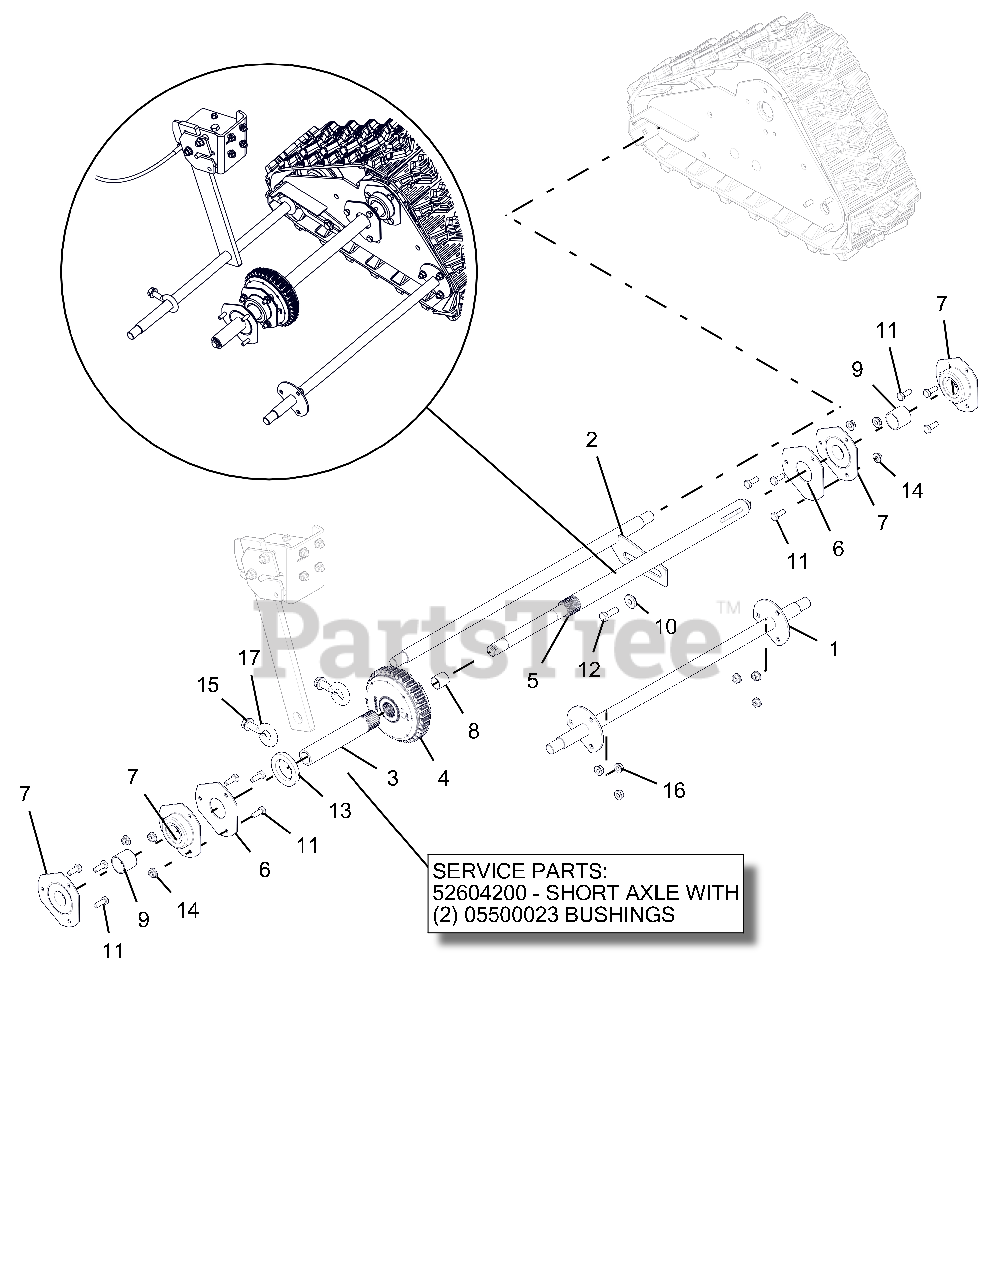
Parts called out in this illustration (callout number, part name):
1	AXLE, FRONT - PRO
2	AXLE, REAR - PRO TRACK
3	AXLE, SHORT-TRACK DIFFERENTIAL
3	AXLE, SHORT-TRACK W/BUSHINGS
3	BSHG-SLV .706X.764X.75 BRZ
4	DIFFERENTIAL, AUTOMATIC
5	AXLE, LONG-PRO AUTO DIFF
6	PLATE, BEARING SPACER
7	BRG-FLG 1.003/1.000 3 BOLT
8	BSHG-SLV .706X.764X.75 BRZ
9	BSHG-SLV, 1.012X1.125X1.00
10	BSHG-FLG .325X.499X.3X.875
11	@BLT-HEX .25-20X.75 GR5 YWZC
12	@BLT-HEX .31-18X1.00 GR5 YWZC
13	WSHR-FL-NY 1.38X2.00X.25
14	@NUT-LK-CTR-FLG .25-20 YWZC
15	NUT-LK-CTR-FLG .38-16 YWZC
16	@NUT-LK-TOP-FLG .25-20 YWZC
17	BLT-EYE .375-16X.880 YWZC
